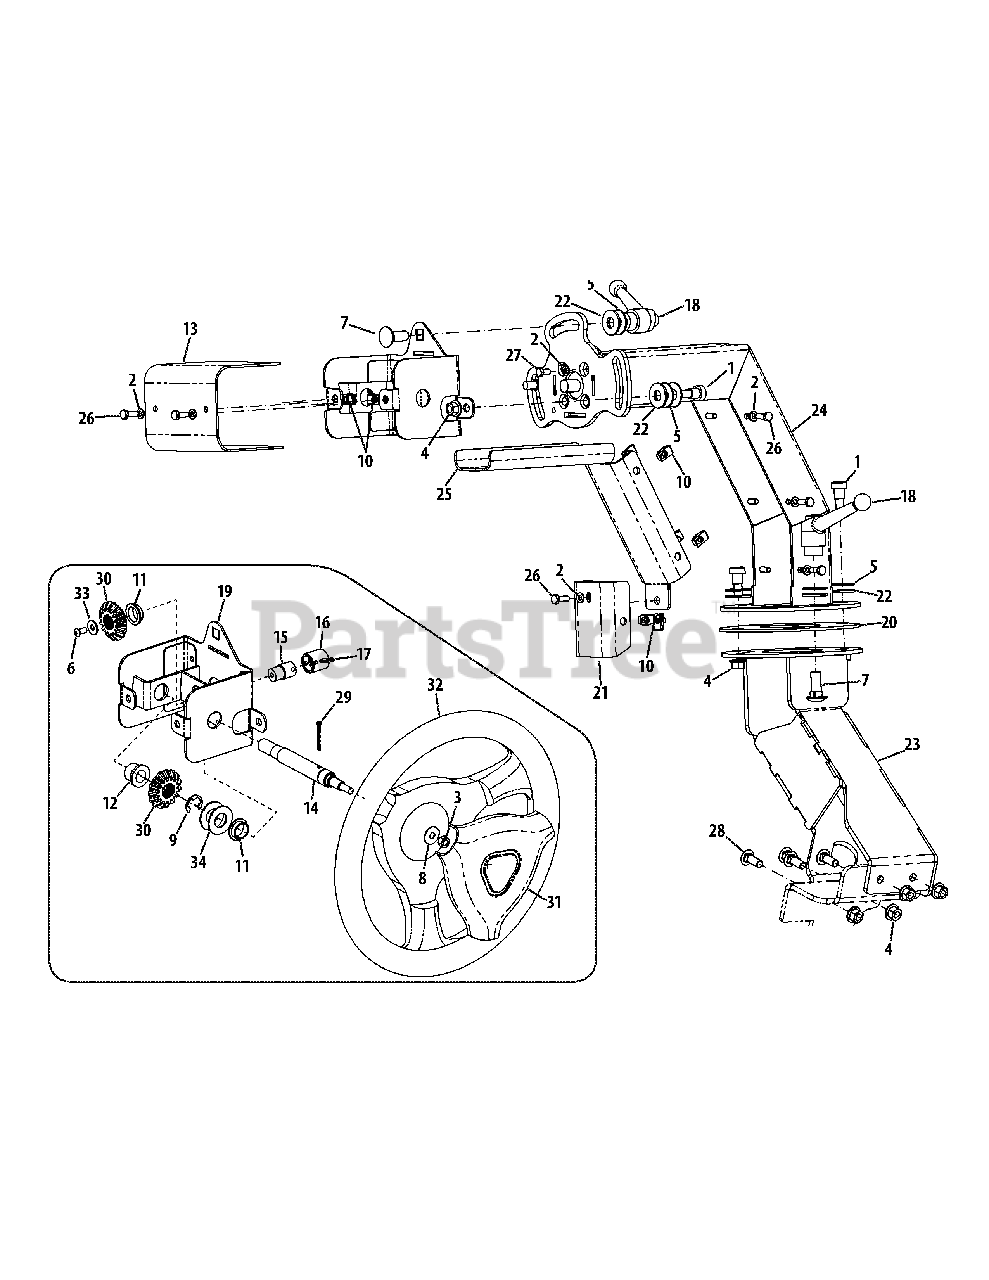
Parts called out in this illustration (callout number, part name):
1	Shoulder Bolt, 3/8-16 x .495 x .500
2	Lock Washer, .250 x .489 x .110
3	Nut, 5/16-24
4	Flange Counter Lock Nut, 3/8-16
5	Washer, .533 x 1.25 x .058
6	Screw, 1/4-20 x .500
7	Carriage Bolt, 1/2-13 x 1.25
8	Bell Washer, .325 x .930 x .045
9	Retainer Clip
10	U-Nut, 1/4-20
11	Flange Bearing, .752 x 1.25 x .305
12	Flange Slv. Bearing, .630 x .875 x .75
13	Box Steering Cover
14	Steering Shaft
15	Valve Steering Shaft
16	Steering Valve Spline Hub
17	Spirol Pin, 3/16 x 1.0
18	Steering Adjust/Lock Lever
19	Steering Box Housing Assembly
20	Wear Swing Plate
21	Steering Column Cover
22	Washer, .531 x 1.250 x .100
23	Base Column Assembly
24	Upper Steering Column Assembly
25	Upper Steering Column Cover
26	Hex Screw, 1/4-20 x .75
27	Hex Screw, M6-1.00 x 14
28	Carriage Bolt, 3/8-16 x 1.00
29	Cotter Pin, 1/8 x 1.25
30	Splined Bore Miter Gear
31	Steering Wheel Cover
32	Steering Wheel
33	Flat Washer, .28 x .74 x .063
34	Flat Washer, .76 x 1.49 x .06
